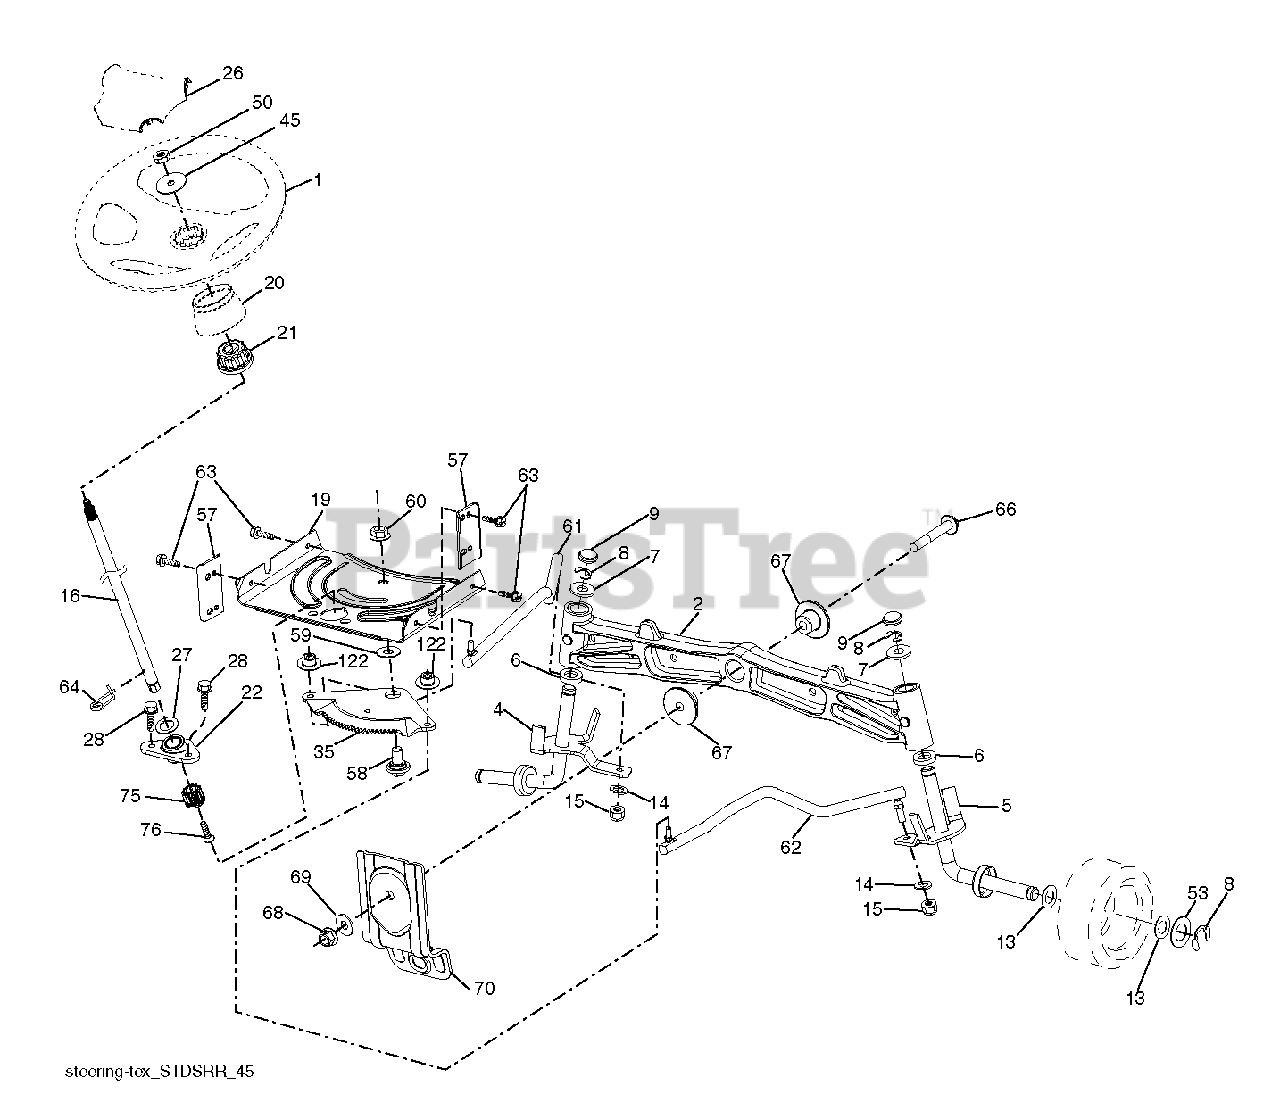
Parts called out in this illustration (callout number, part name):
1	WHEEL.STEER.HUSQ.SR.498.OVMLD
2	AXLE.CAST.IRON
4	SPINDLE.WELDED.LH.15"TEX
5	SPINDLE.WELDED.RH.15"T
8	RING CLIP
9	CAP.SPINDLE
14	WASHER, LOCK 3/8
15	NUT CROWNLOCK 3/8-24
16	Steering Shaft Service Kit
19	PLATE.STEER.DDL.NLT/NG
21	Steering Shaft Adapter Kit
22	Steering Shaft Service Kit
26	INSERT.CAP.WHL.STRG.HUSQ.PREM
27	WASHER LT
28	SCREW, 3/8-16X3/4
35	GEAR.SECTOR.PLATE.DDL.
45	WASHER.3/8ID.2-3/8OD.12GA.PLTD
50	NUT LOCK FLG 3/8-16 UNC
53	WASHER.HARDENED
57	BRACKET.UPSTOP.TEX
58	BOLT.SHOULDER.SECTOR.P
59	WASHER.THURST.SECTOR.S
60	NUT FLANGE LOCK 5/8-11
61	DRAGLINK.LH.BALLSTUD.D
62	DRAGLINK.RH.BALLSTUD.D
63	SCREW
64	RETAINER.CLIP.SPRING.S
66	BOLT HEX FGHD 7/16-14 X 3 SERR
67	BUSHING.PM.FRONT AXLE
68	NUT.LOCK.FLANGE.7/16
69	WASHER.1.5X.505X.118
70	Deck Suspension Bracket, Front RR
75	Steering Shaft Pinion Kit
76	Screw Head Socket Lrvb
